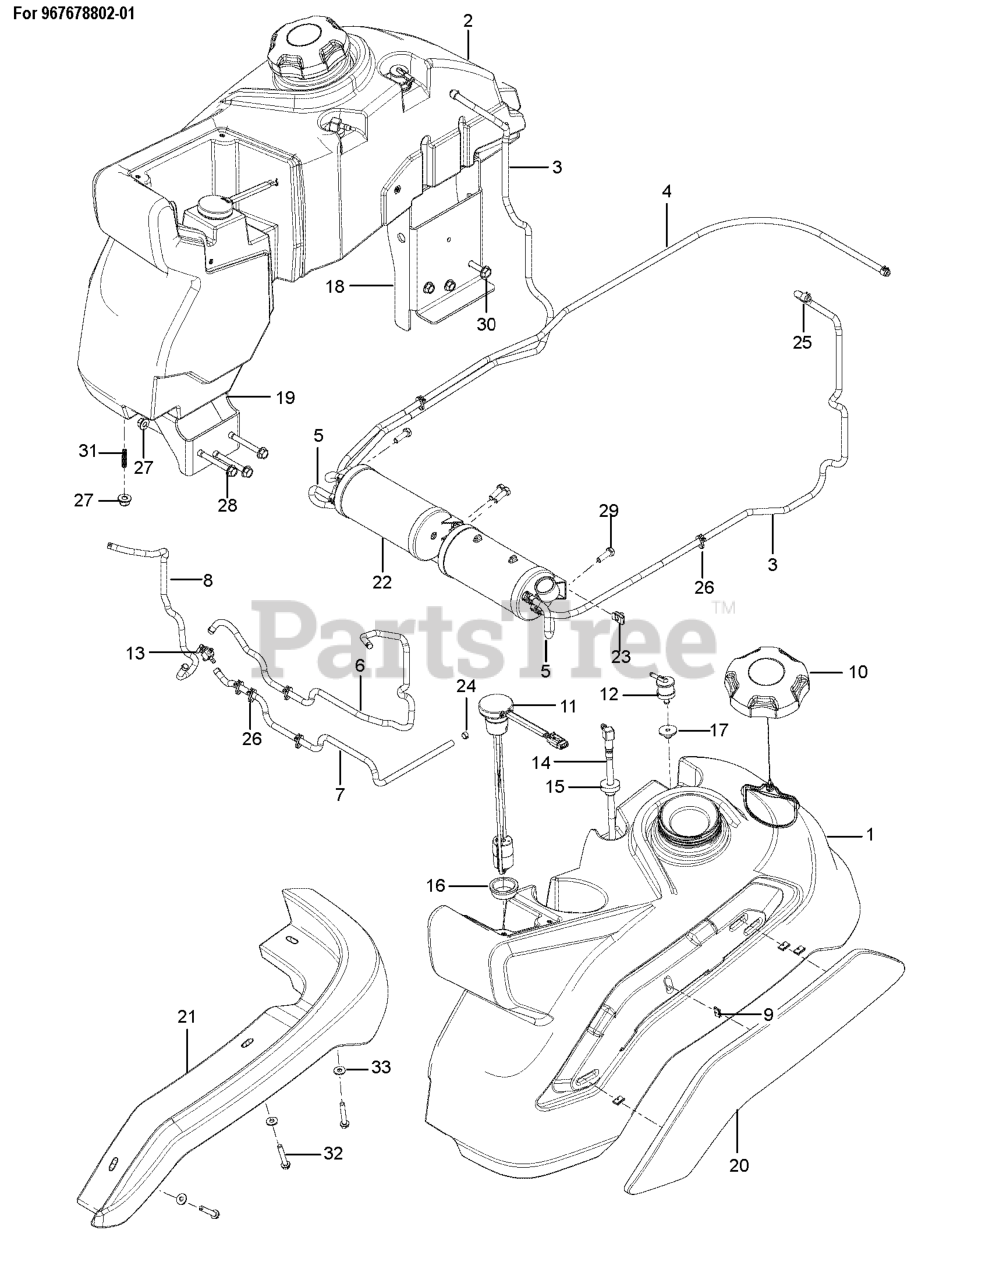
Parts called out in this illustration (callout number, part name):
1	FUEL.TANK.ASM.LH.PZ.REFRESH.18
2	FUEL.TANK.ASM.RH.PZ.REFRESH.18
3	HOSE.3/16".VAPOR.LINE.42"LGTH
4	HOSE.3/16".VAPOR.LINE.55"LGTH
5	HOSE 3/16" VAPOR LINE 13" LENG
6	HOSE.1/4".LOW.PERM.FUEL.LN.46"
7	HOSE.1/4".LOW.PERM.FUEL.LN.33"
8	HOSE.1/4".LOW.PERM.FUEL.LN.24"
9	CLIP.U-TYPE
10	CAP, FUEL
11	SENSOR.FUEL.LVL.FLOAT.V500
12	VALVE.FUEL.CHECK
13	FUEL VALVE
14	TUBE.ASM.FUEL.TANK.PICK-UP.LH
15	BUSHING OUTLET T
16	GROMMET, FUEL SENSOR
17	GROMMET.CHECK.FUEL
18	BRACKET.FUEL.TANK.REAR.SUP.431
19	BRACKET.FUEL.TANK.REAR.SUP.431
20	COVER.LH.FUEL.TANK/CONSOLE APP
21	GUARD.MUD.LH
22	CANISTER.FLEX.6.3GAL3/16".TANK
23	1/4-20 U NUT
24	HOSE CLAMP
25	CLAMP, HOSE
26	TIE WRAP, 8-3/8", W/CLIP
27	5/16-18 NYLOC FLANGE NUT
28	BOLT HEX FLGHD 5/16-18X3 GR. 5
29	BOLT
30	SCREW
31	SCREW.5/16-18X1.25"THREADED
32	SCREW.1/4-20X1.5IN.HEX.MACH
33	WASHER
